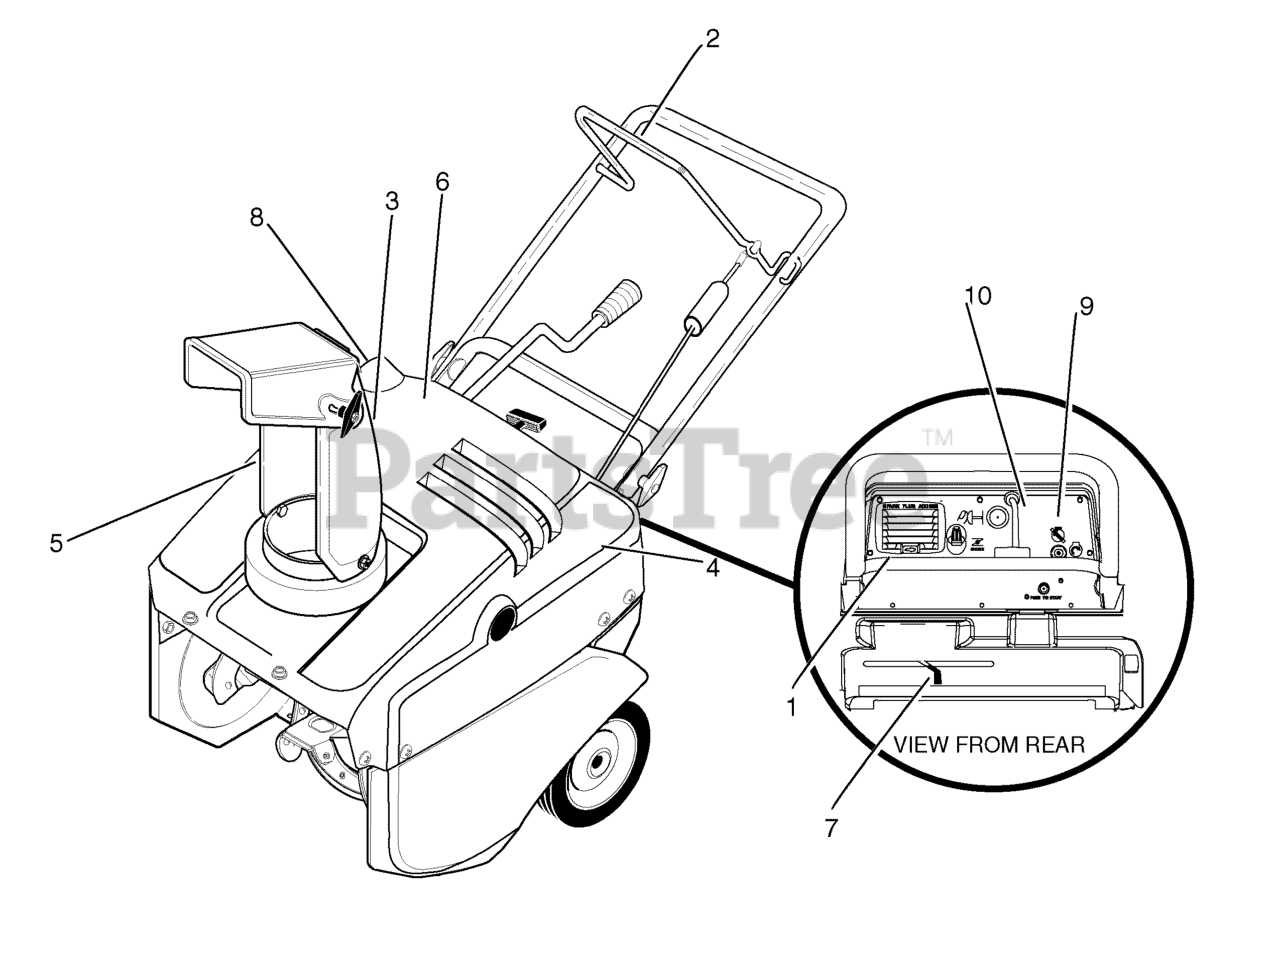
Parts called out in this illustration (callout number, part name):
1	DECAL, SPARK PLUG ACCESS
2	DECAL, AUGER CONTROL BAR
3	DECAL, DANGER CHUTE
4	DECAL, DANGER MUFFLER
5	DECAL, DANGER AUGER
6	DECAL, ODEC MURRAY 5.0/21
7	DECAL, OFF-CHOKE-ON
8	DECAL, EPA 5HP
9	DECAL, ELECTRIC START COVER UP
10	DECAL, DASH 21"
